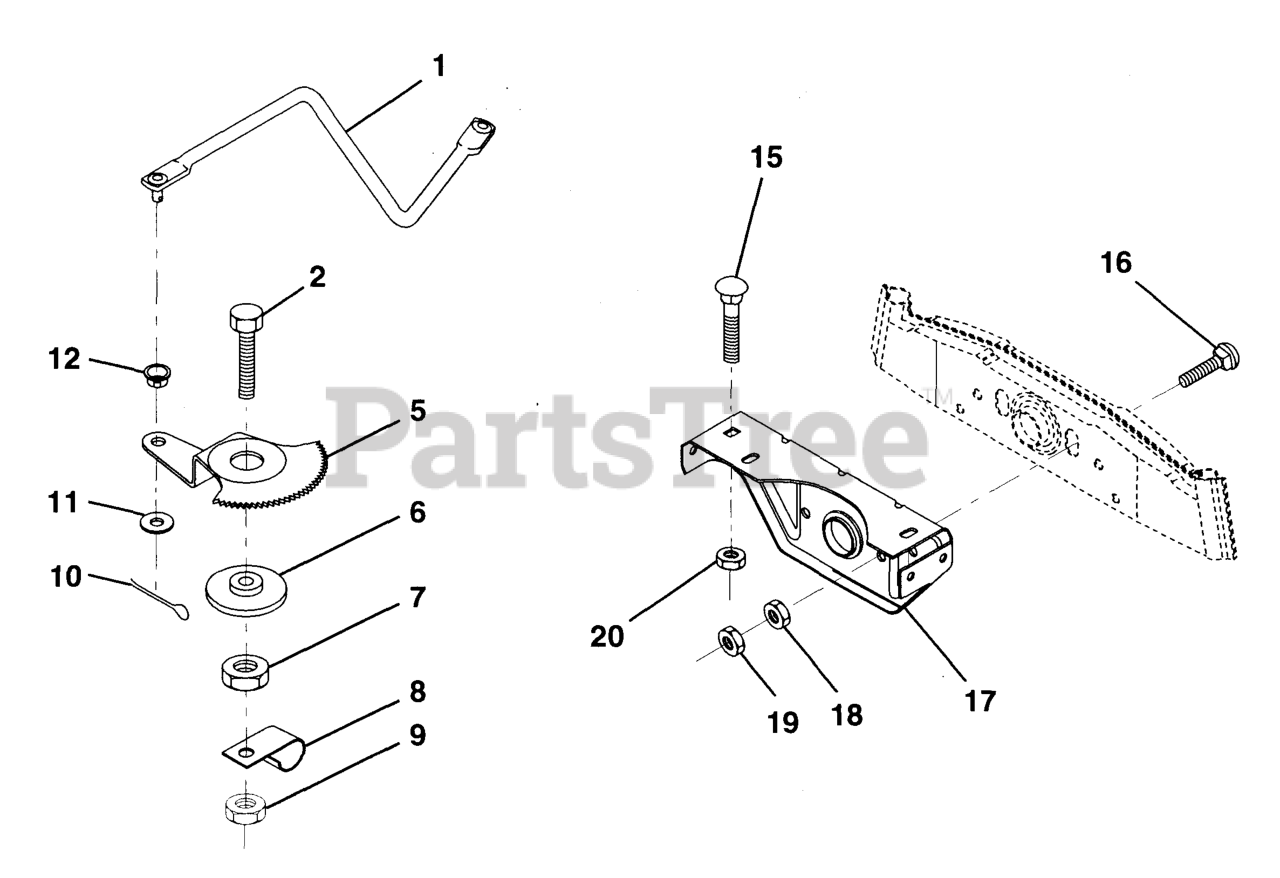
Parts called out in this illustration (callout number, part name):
5	GEAR SECTOR
7	NUT
8	CLIP INSULATOR
9	NUT LTV
10	COTTER PIN
11	WASHER
12	BUSHING.DRAGLINK (2 2)
15	BOLT
16	BOLT
17	SUPT,FRT AXLE
18	NUT.HEX.3/8-16UNC
19	LOCKNUT
